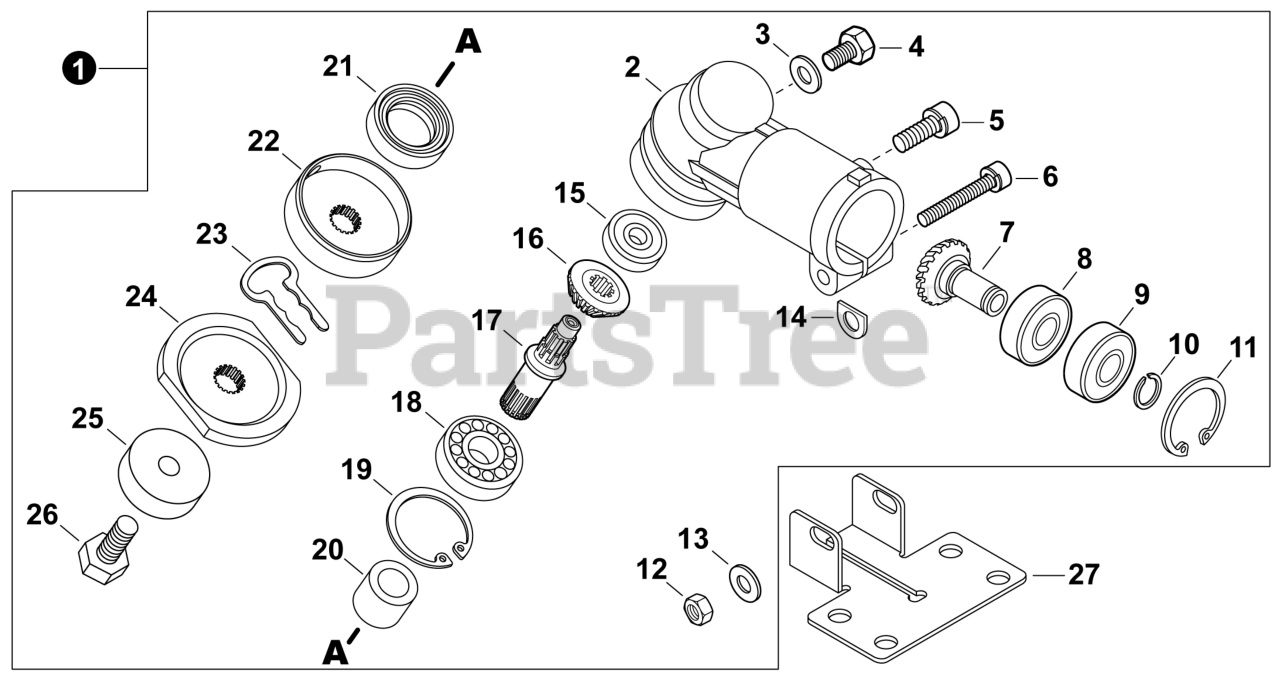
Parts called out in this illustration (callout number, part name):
1	GEAR CASE ASSY
2	HOUSING, GEAR CASE
4	BOLT M6x10
5	BOLT 5x16
6	BOLT M5x35
7	GEAR, PINION
8	BEARING, BALL 608
9	BEARING, BALL 608ZZ
10	E-RING 8
11	RING, SNAP 22
13	WASHER 5.5x12x0.8
14	D-WASHER
15	BEARING, BALL 626 DDU
16	GEAR, BEVEL
17	SHAFT, GEAR
18	BEARING, BALL 6000
19	RING, SNAP 26
21	SEAL, OIL
22	PLATE, ADAPTOR - UPPER
23	CLIP, BLADE
24	PLATE, ADAPTOR - LOWER
25	GUARD, BOLT
26	BOLT M7x18
27	PLATE, SHIELD MOUNTING
